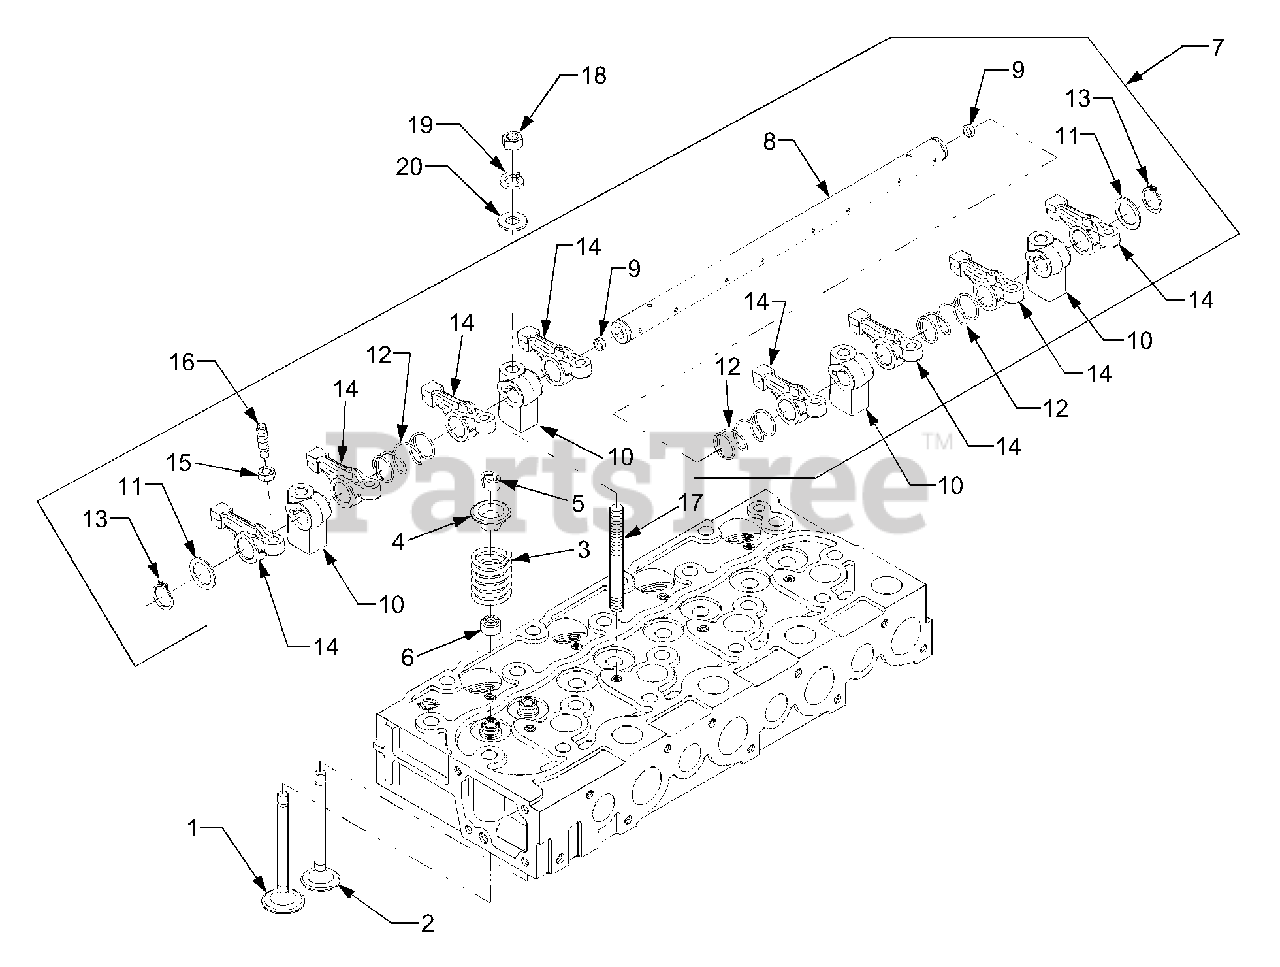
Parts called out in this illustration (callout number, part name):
2	Valve, Outlet
3	Spring, Valve
4	Retainer, Valve Spring
5	Collet, Valve Spring
6	Seal, Valve Stem
7	Rocker Arm Shaft Ass'y
8	Shaft, Rocker Arm
10	Bracket, Rocker Arm
11	Washer, Plain
12	Spring, Rocker Arm
15	Nut, Adjusting
16	Screw, Adjusting
17	Stud, Rocker Arm
19	Washer, Spring
20	Washer, Plain
